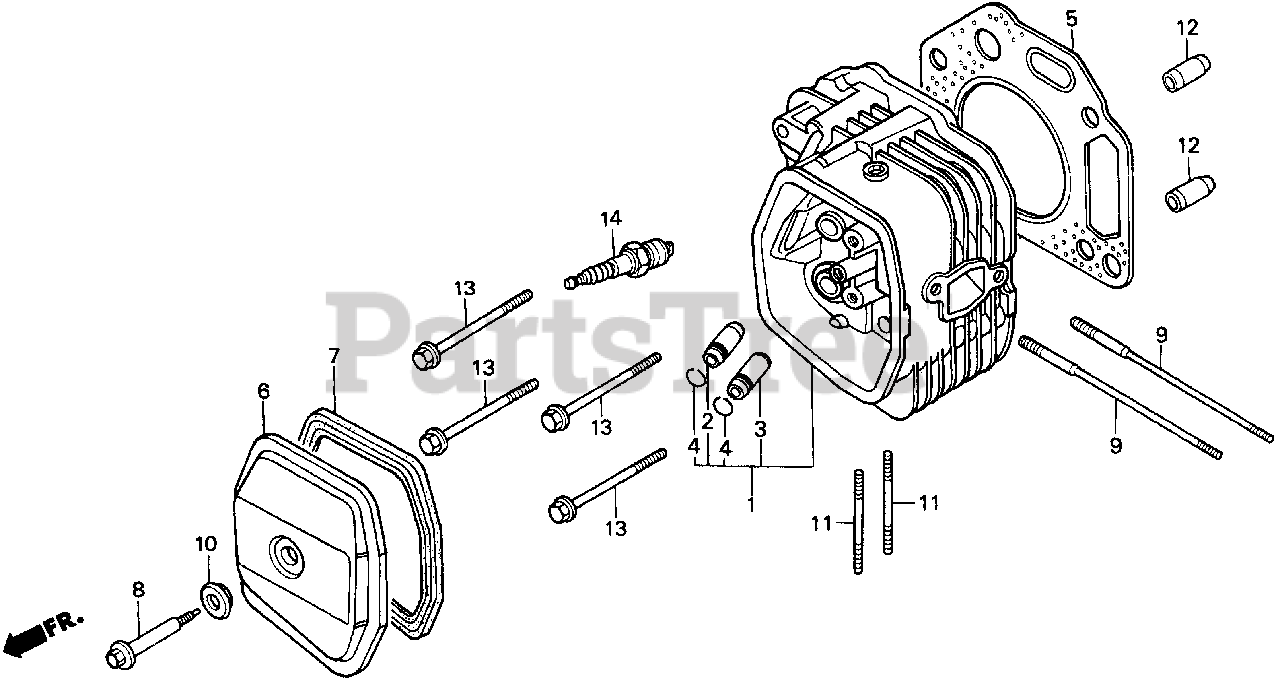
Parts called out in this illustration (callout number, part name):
1	CYLINDER HEAD
2	GUIDE, VALVE (OS)
2	GUIDE, VALVE (OVER SIZE)
3	GUIDE, EX. VALVE (OS)
4	CLIP, VALVE GUIDE
5	GASKET, CYLINDER HEAD
6	COVER, HEAD
7	GASKET, CYLINDER HEAD COVER
8	BOLT, HEAD COVER
9	BOLT, STUD (8X138.5)
10	WASHER, HEAD COVER
11	BOLT, STUD (8X22)
12	PIN A, DOWEL (12X20)
13	BOLT, FLANGE (10X80)
14	SPARK PLUG (BPR5ES) (NGK)
14	SPARK PLUG (W16EPR-U) (DENSO)
